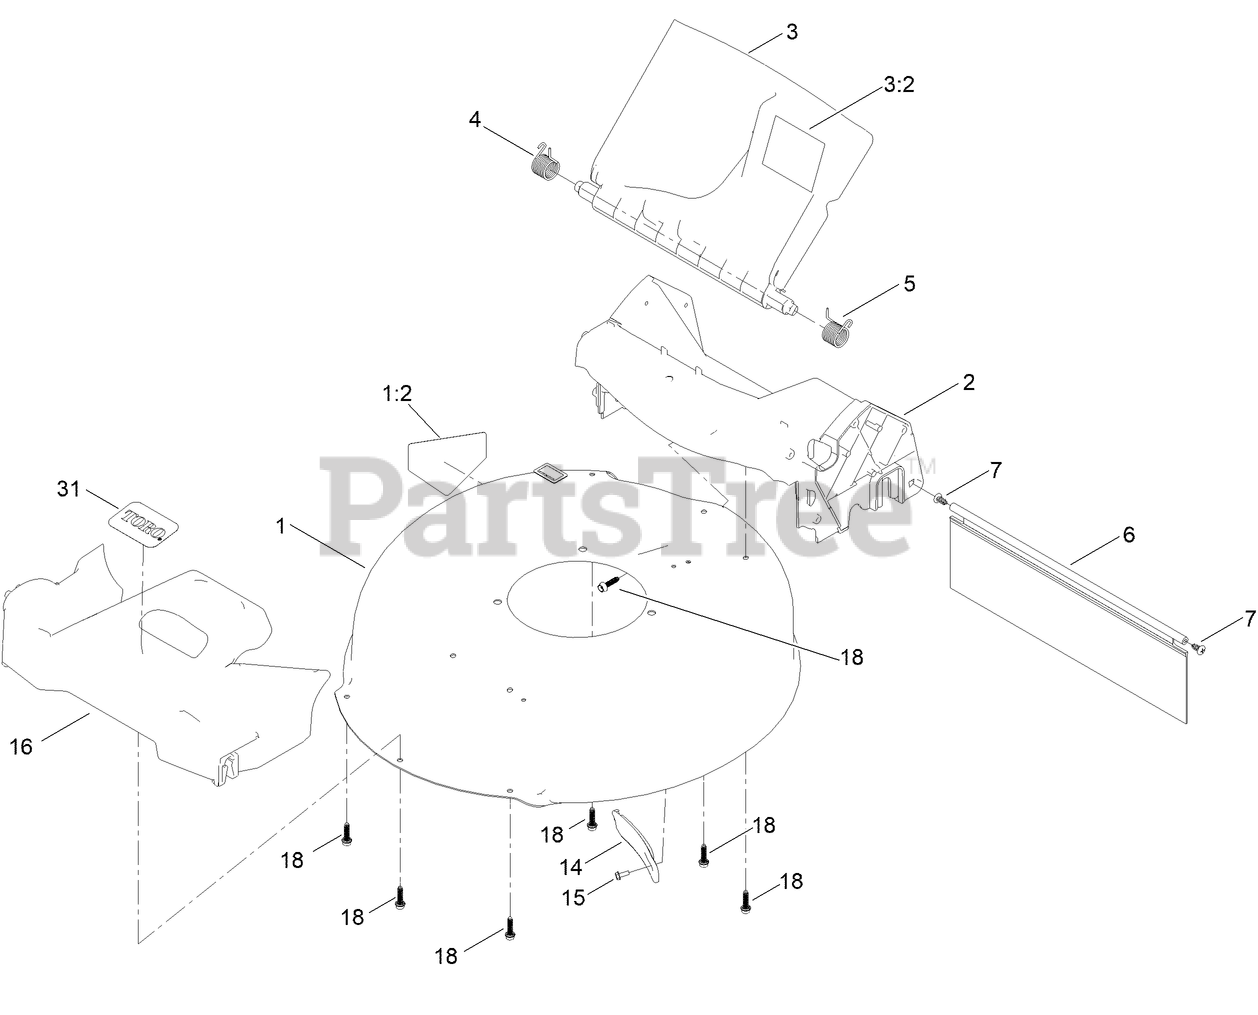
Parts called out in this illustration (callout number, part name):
1	HOUSING ASM
1:2	DECAL-DANGER
2	CHUTE-SP/AWD, 21 IN
3	DEFLECTOR-REAR ASM
3:2	DECAL-WARNING
4	SPRING-TORSION
5	SPRING-TORSION
6	SHIELD-TRAILING
7	SCREW-PTH
14	COVER-BELT
15	SCREW-TAPTITE
16	BUMPER
18	SCREW-FLANGE, PLASTIC
31	DECAL-TORO, SILVER
